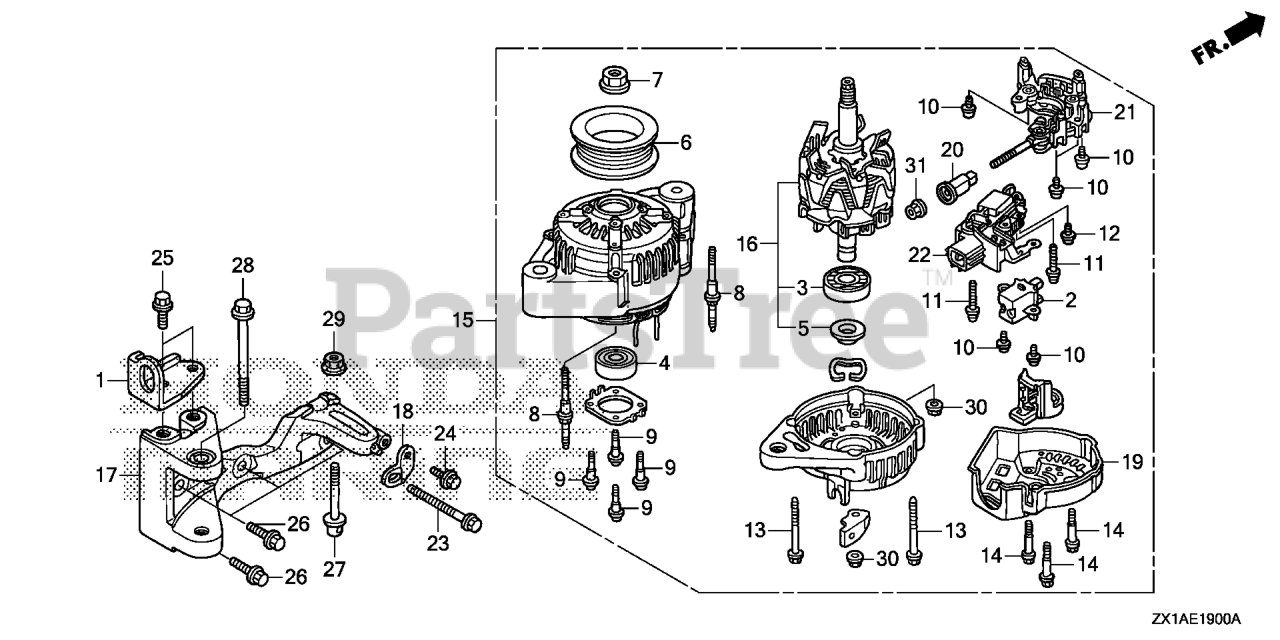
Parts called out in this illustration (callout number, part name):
1	HANGER B, ENGINE
2	HOLDER ASSY., BRUSH
3	BEARING, RR.
4	BEARING, FR.
5	COVER, BEARING
7	NUT, PULLEY LOCK
8	BOLT, STUD
10	SCREW-WASHER
11	SCREW-WASHER (4X25)
13	BOLT-WASHER
15	ALTERNATOR ASSY.
16	ROTOR ASSY.
17	BRACKET, ALTERNATOR
18	STAY, ALTERNATOR
19	END COVER, RR.
20	BUSH, INSULATION
21	RECTIFIER ASSY.
22	REGULATOR ASSY.
23	BOLT, SPL ADJ
23	BOLT, SPECIAL ADJUSTER
24	BOLT, FLANGE (6X16)
25	BOLT, FLANGE (8X20)
26	BOLT, FLANGE (8X28)
27	BOLT, TENSIONER
28	BOLT, FLANGE (10X80)
29	NUT, FLANGE (8MM)
30	NUT-WASHER (5MM)
31	NUT, HEX. (6MM)
